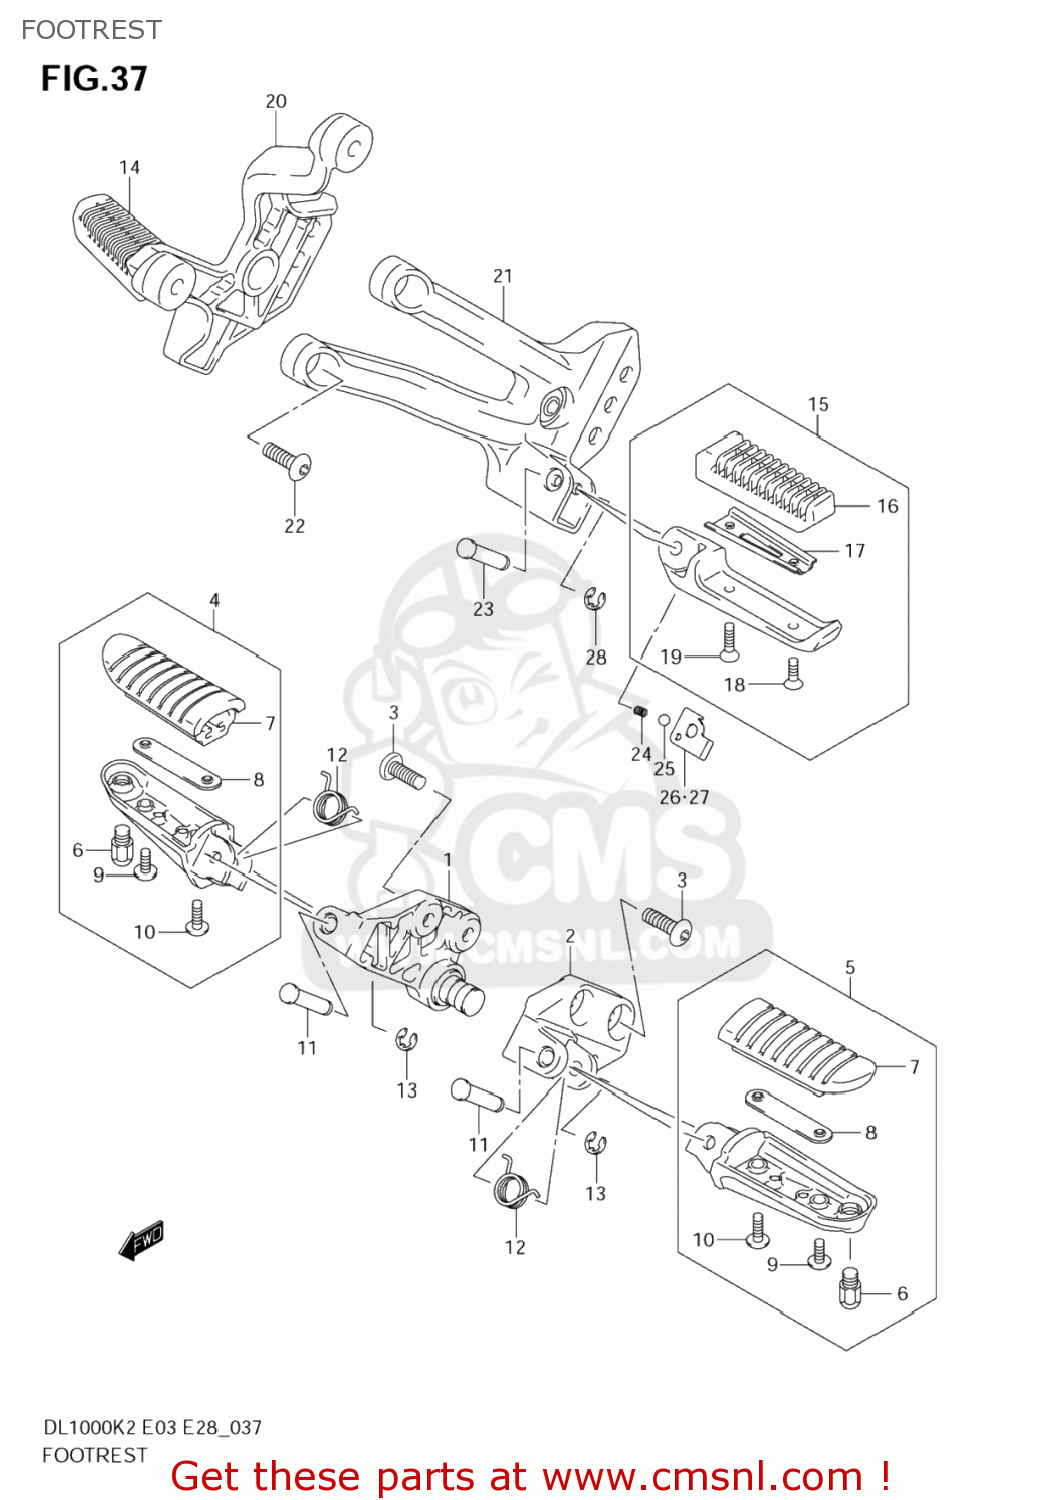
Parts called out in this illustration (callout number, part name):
1	BRACKET COMP,F
2	BRACKET,FR FOOTREST,L
3	BOLT(8X23)
4	FOOTREST ASSY,
5	FOOTREST ASSY,
6	BOLT,BANK SENSOR
7	RUBBER,FOOTREST
8	PLATE,FR FOOTREST RUBBER
9	SCREW
10	SCREW 5X20
11	PIN
12	SPRING
13	E.RING
14	FOOTREST ASSY,PILLION,R
15	FOOTREST ASSY,PILLION,L
16	RUBBER,RR FOOTREST
17	PLATE,RUBBER STOPPER
18	SCREW
19	SCREW,SUNVISOR
20	BRACKET,PILLIO
21	BRACKET,PILLION FOOTREST,L
22	BOLT(8X23)
23	PIN(8X33.2)
24	SPRING
25	BALL
26	PLATE,PILLION FOOTREST,R
27	PLATE,PILLION FOOTREST,L
28	E.RING
